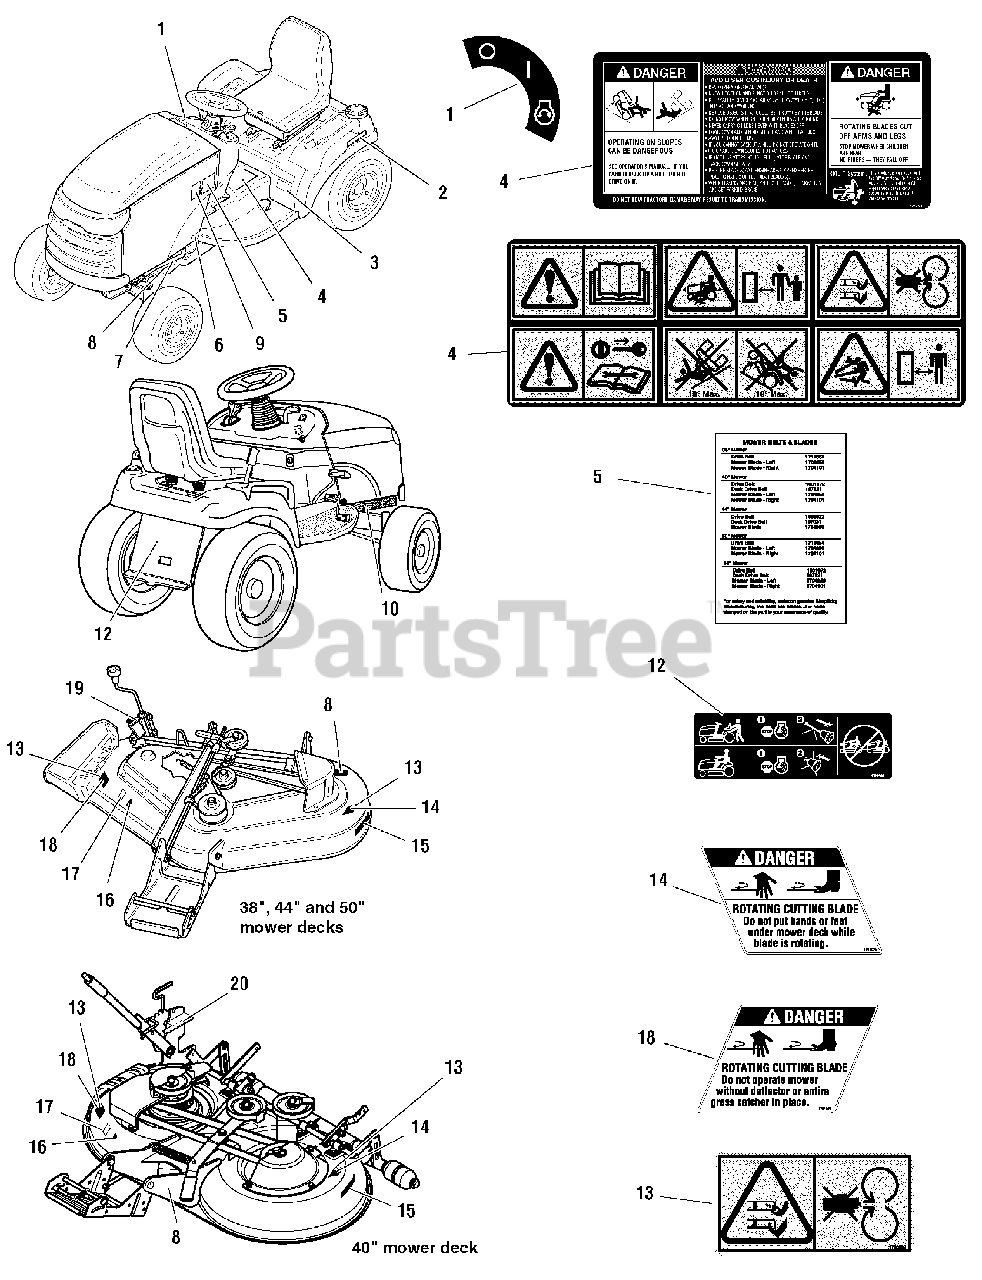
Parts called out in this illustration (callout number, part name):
1	DECAL, Ignition Switch Symbols, White/Black
2	DECAL, Automatic Control Traction
3	DECAL, 18HP
3	DECAL, 20HP
4	DECAL, Tunnel Cover, Danger Slopes/Blades
4	DECAL, Tunnel Cover, Danger Slopes/Blades, (Export)
5	DECAL, Drive Belts, Mower Blades
6	DECAL, Protective Sticker
7	LABEL, Decibel, Power Mass (Export)
8	DECAL, I.D. Plate
9	DECAL, Touch Up Paint (Orange)
9	DECAL, Touch Up Paint (Red)
10	DECAL, Patent
12	DECAL, Transmission Release Valve
13	DECAL, Danger Rotating Blades (Export)
14	DECAL, Danger Do Not Put Hands/Feet in Mower
15	DECAL, Free Floating Mower, Silver
16	DECAL, OPEI Certified
17	DECAL, 38", Silver on Black with Stripe
17	DECAL, 40", Silver on Black with Stripe
17	DECAL, 44", Silver on Black with Stripe
17	DECAL, 50", Silver on Black with Stripe
18	DECAL, Danger Do Not Operate Without Deflector
19	DECAL, Height of Cut, 38", 44" & 50"
20	DECAL, Height of Cut, 40"
